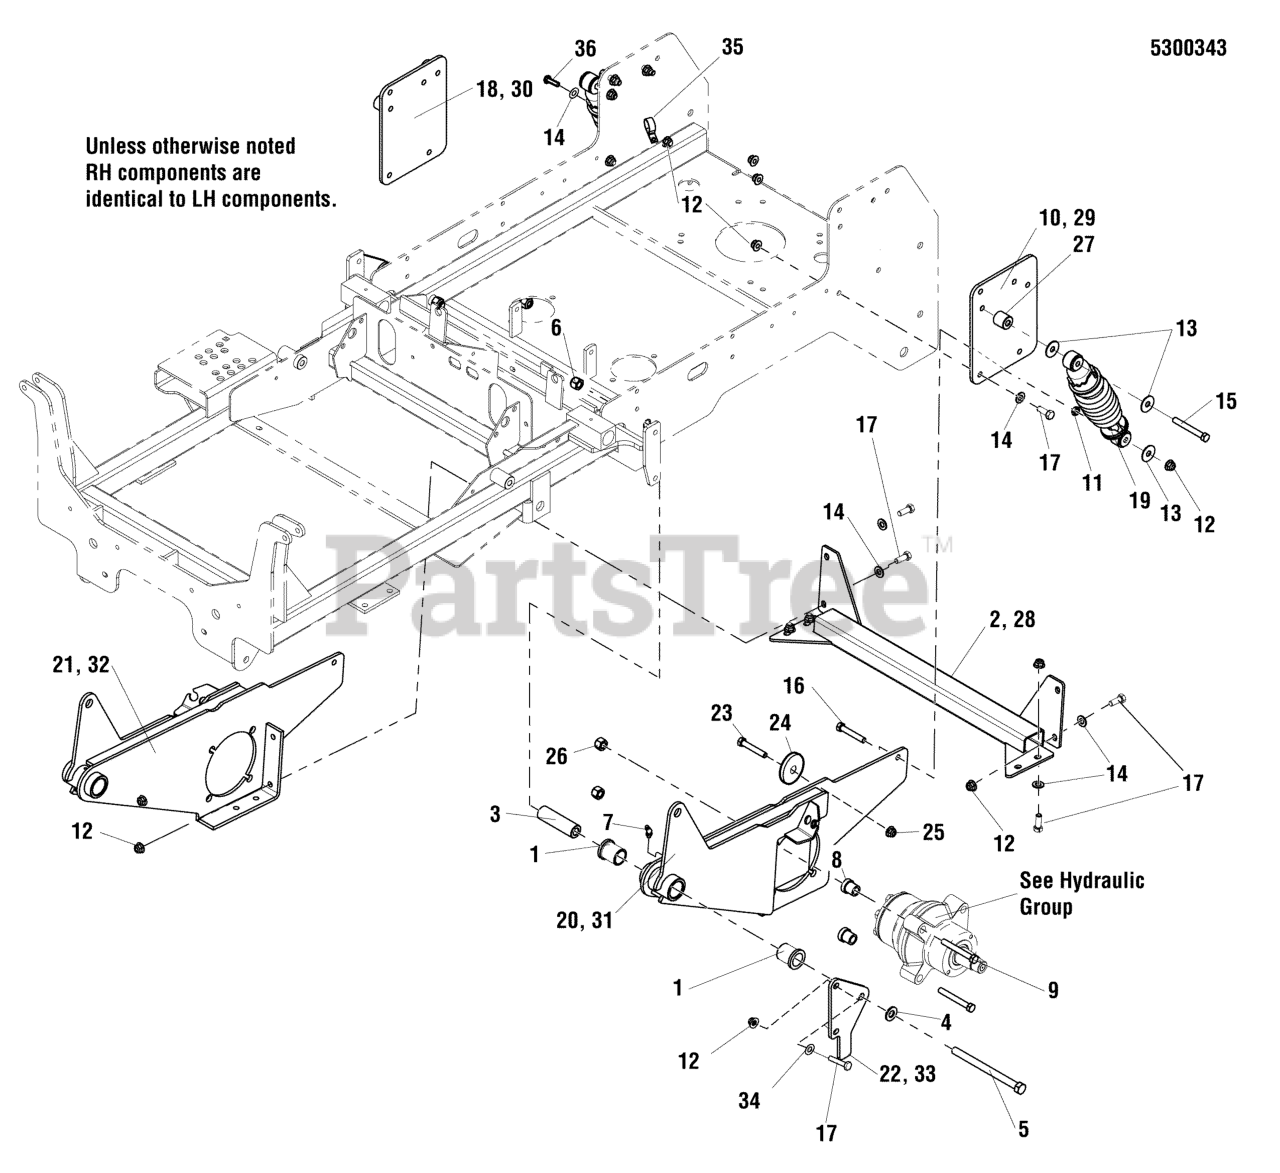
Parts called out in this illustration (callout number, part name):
1	BUSHING, FLANGE
2	KIT, TIE BAR, 52
3	SPACER, .52 X 1.00 X 3.42
4	WASHER, 1/2" GD9 YZ
5	BOLT, 1/2-13 X 6-1/2" GD8 YZ
6	NUT, 1/2-13 HEX NYLON LOCK
7	GREASE FITTING, 45 DEGREE
8	SPACER, .51 X .75 X .56
9	BOLT, 1/2-13 X 3" GD5 CZ
10	PLATE, FRAME SUPPORT, LH - RED
11	SPACER, .39 X 1.00 X .50
12	NUT, 3/8-16 HEX NYLOCK FLANGE
13	WASHER, 3/8" FENDER
14	WASHER, 3/8 SAE
15	BOLT, 3/8-16 X 3" GD5 CZ
16	BOLT, 3/8-16 X 2-1/4" GD5 TFL
17	BOLT, 3/8-16 X 1-1/4" GD5 CZ
18	WELD, FRAME SUPPORT - RH - RED MODEL
19	COIL-OVER SHOCK ASSEMBLY
20	WELD, MOTOR MOUNT - LH - RED MODEL
21	WELD, MOTOR MOUNT - RH - RED MODEL
22	SUPPORT, SWING ARM - BLK
23	SCREW, 5/16-18 X 1, PHILLIPS HD, BZ
24	SPACER, .34 X 1.54 X .25 UHMW
25	NUT, 5/16-18 HEX NYLOCK FLANGE
26	NUT, 1/2-13 SQUARE
27	SPACER, SHOULDER
28	WELD, TIE BAR - BLK
29	PLATE, FRAME SUPPORT, LH - ORANGE MODEL
30	WELD, FRAME SUPPORT - RH - ORANGE MODEL
31	WELD, MOTOR MOUNT - LH - ORANGE MODEL
32	WELD, MOTOR MOUNT - RH - ORANGE MODEL
33	SUPPORT, SWING ARM - BLK
34	WASHER, 3/8" GD.9 FLAT
35	CLAMP, VINYL INSULATED
36	BOLT, 3/8-16 X 1-1/4" GD5 CZ
